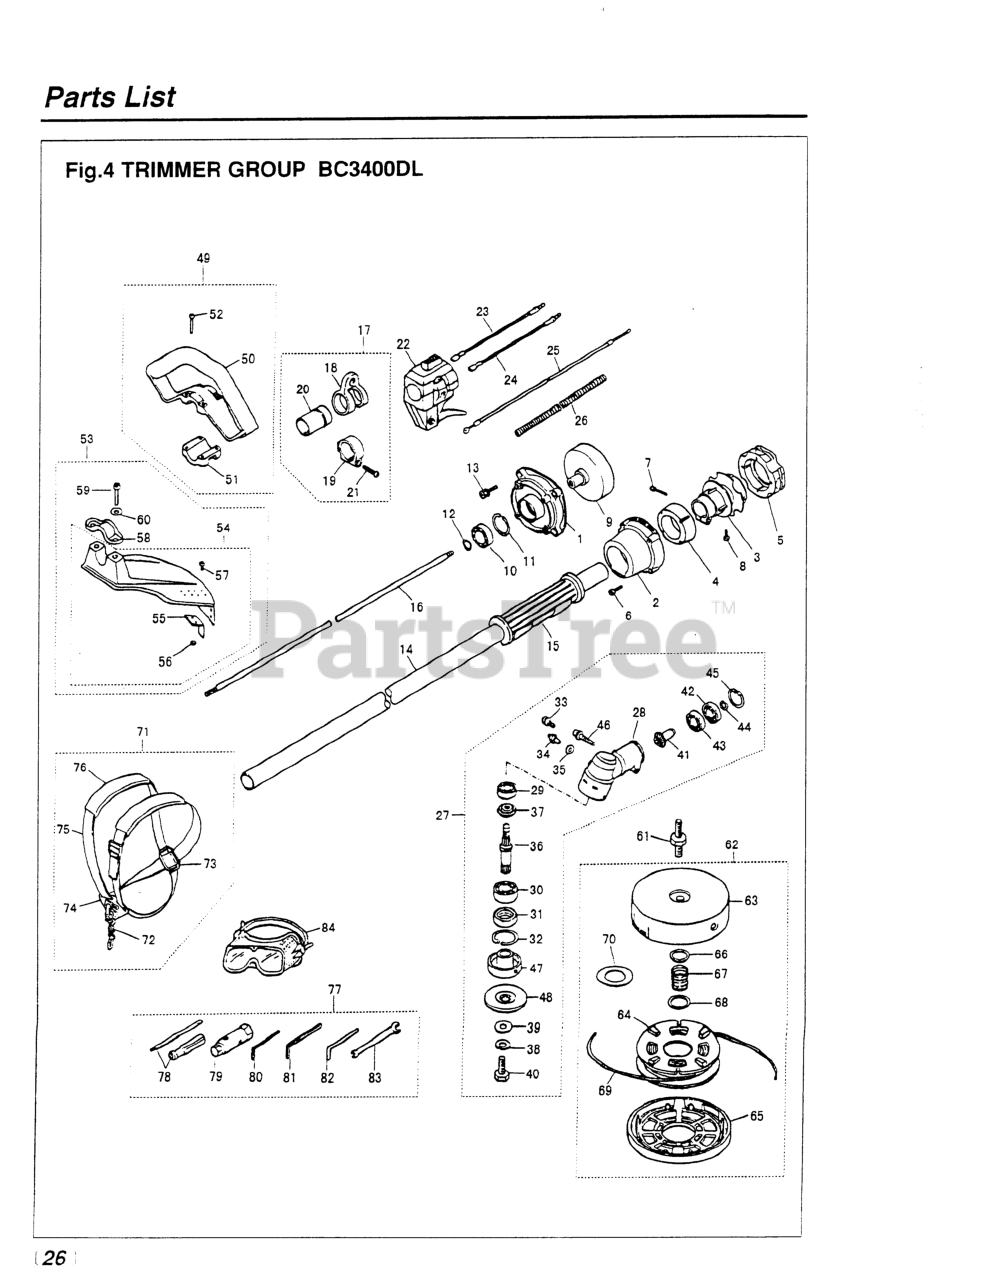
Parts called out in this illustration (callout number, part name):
1	HOUSING
2	CAP
3	JOINT
4	ABSORBER-F
5	ABSORBER-R
6	BOLT, M5 X 30
7	BOLT, M6 x 30
8	BOLT, M5 X 10
10	BEARING
11	RING, SNAP, M35 X 1.5
12	RING, SNAP, M15 X 1.0
13	BOLT, M6 x 20
14	PIPE COMP.
16	SHAFT, DRIVE (USE -12211)
17	HANGER ASSEMBLY
18	HANGER
19	CLAMP
21	SCREW, M5 x 25
23	CORD (A), BLACK
24	CORD (B), RED
25	CABLE COMP (RPLS 1633-83100)
26	TUBE
28	GEARCASE (RPLS -13113)
29	BEARING (RPLS T3403-13510)
31	SEAL, OIL
32	RING, SNAP, M32 x 1.2
33	BOLT, M5 X 10
34	FITTING, GREASE
35	WASHER, M6 X .8
36	SHAFT
37	GEAR, BEVEL
38	WASHER (RPLS 3180-13270)
39	WASHER, M8 x 2.3 (RPLS -20823)
40	BOLT, LH
41	PINION
43	BEARING (RPLS T3403-13510)
44	RING, SNAP
45	RING, SNAP, M26 X 1.2
46	BOLT, M6 x 1.35
47	HOLDER (A)
48	HOLDER (B)
49	HANDLE ASSEMBLY
50	HANDLE
51	CLAMP
52	SCREW, M5 x 35
53	GUARD ASSY (RPLS -24001)
54	GUARD COMP
55	BLADE
56	NUT
57	SCREW, M5 x 12
58	CLAMP
59	BOLT, M6 x 1.30
60	WASHER, M6 X 15
61	SHAFT (RPLS 3274-99120)
62	6
63	CASE (USE -99112)
65	COVER
66	PLATE, LARGE
68	PLATE, SMALL
69	CORD
70	SPACER
74	HANGER COMP.
75	BAND (NOT SOLD SEPARATELY)
76	PROTECTOR
77	TOOL SET
78	SCREWDRIVER
80	WRENCH (TOOL)
81	WRENCH (TOOL)
82	BAR
83	SPANNER, 8 X 10 (RPLS 2540- )
